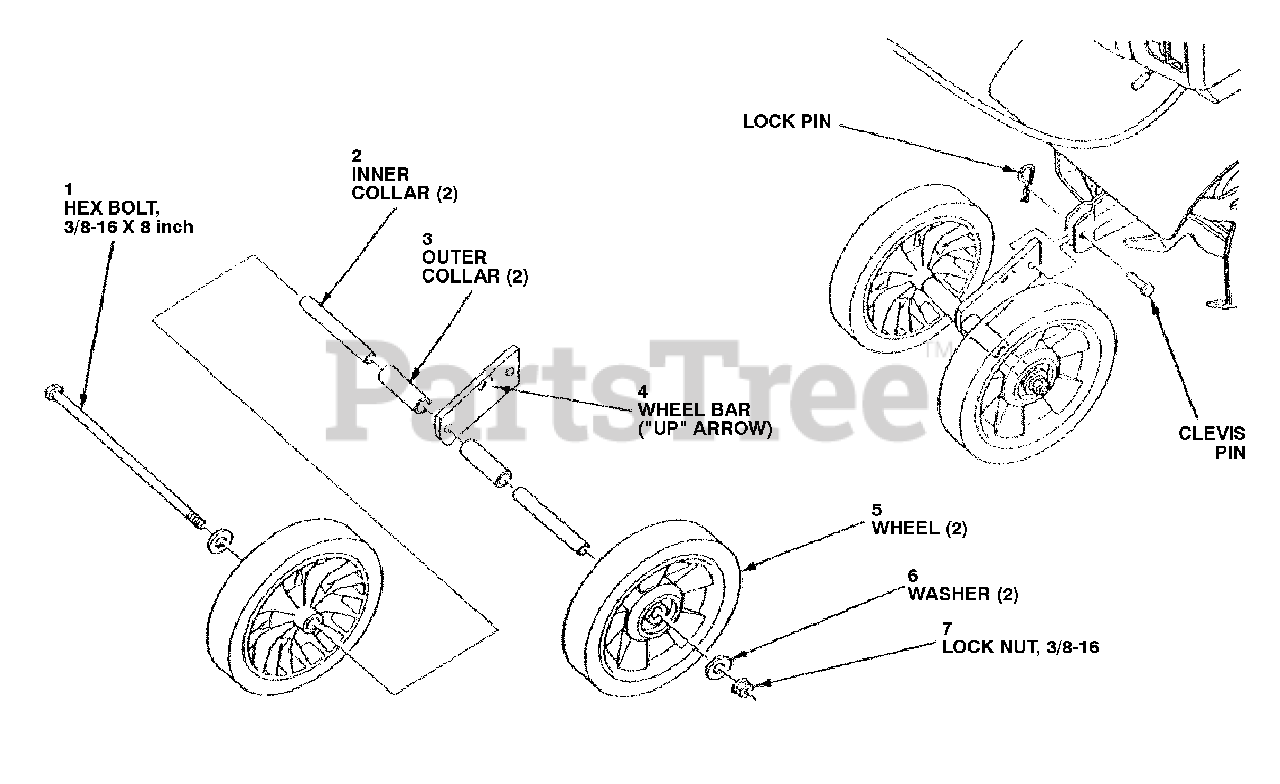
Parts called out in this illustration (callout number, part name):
1	Hex Bolt 3/8-16 x 8
2	Inner Collar
3	Outer Collar
7	Lock-Nut, 3/8-16
7	CT20 Decal
